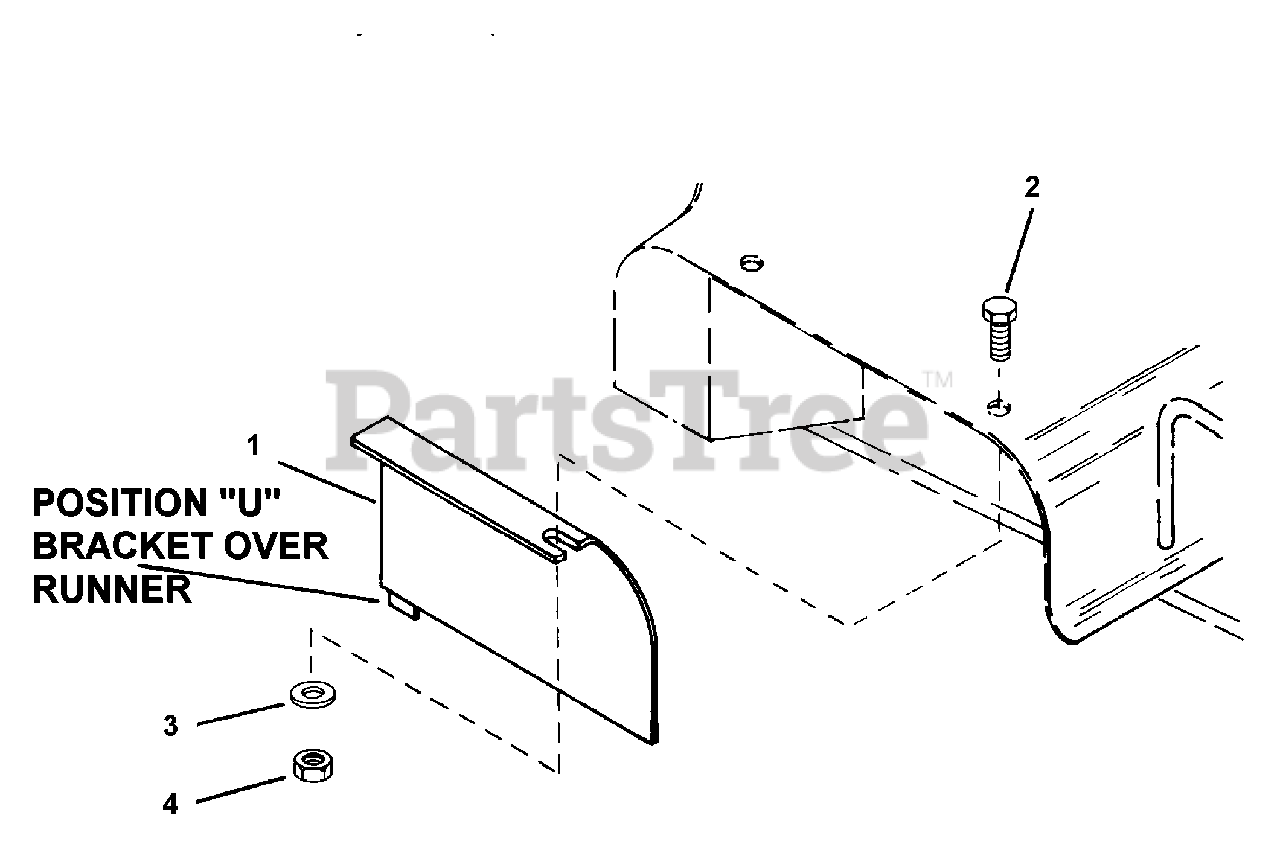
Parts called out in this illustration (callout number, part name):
1	LEAF MULCHER KIT-FAIRWAY
2	BLT-SERHFWH .31-18X.62 PL
3	BEVEL GEAR
4	NUT-LK .312-18 GR A PL
